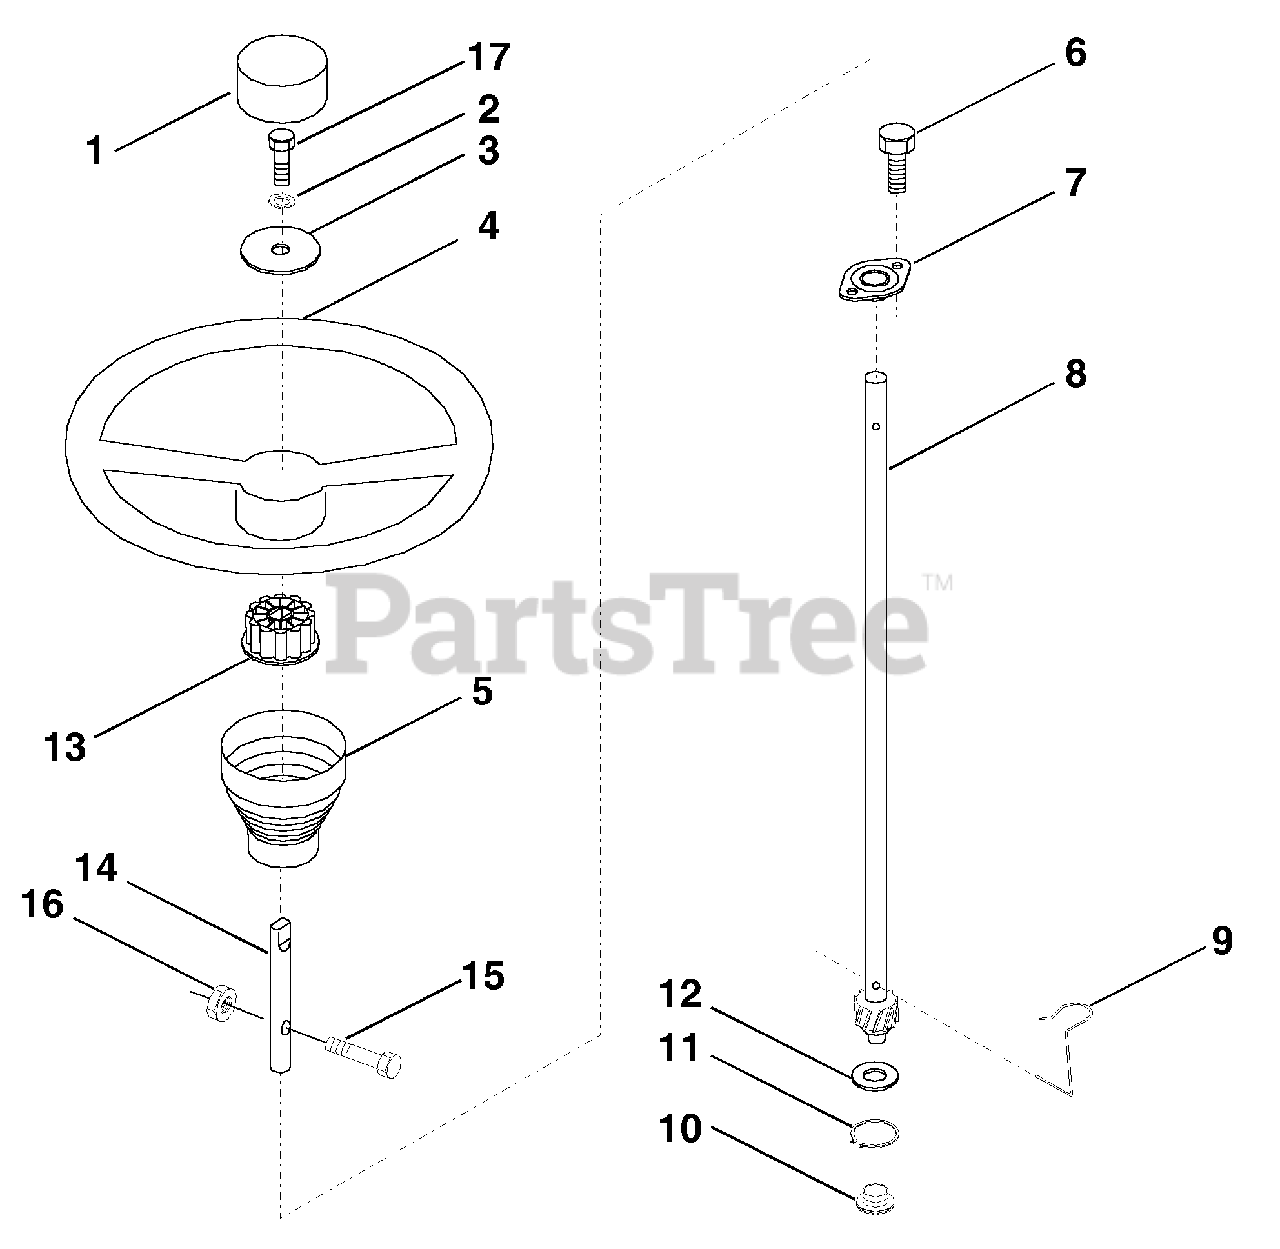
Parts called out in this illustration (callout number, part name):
1	Insert, Wheel, Steering
2	Washer, Lock hvy HLCL SPR 3/8
3	Washer 12/32 x 2-3/8 x 8 Ga.
4	Wheel, Steering
5	Sleeve, Steering
6	Screw, TT #10-32.5.3/8 flange
7	Bushing, Steering
8	Shaft, Steering
9	Clip, Steering
10	Bushing, Lower, Steering
11	Ring, Retaining
12	Washer 21/32 x 1 x 16 Ga.
13	Adaptor, Wheel, Steering
14	Extension shaft steering
15	Bolt Fin Hex 5/16-18 UNC x 1-1/4
16	Nut Lock Hex W/Ins. 5/16-18 UNC
17	Bolt fin Hex 3/8-16 UNC x 1. Gr. 5
